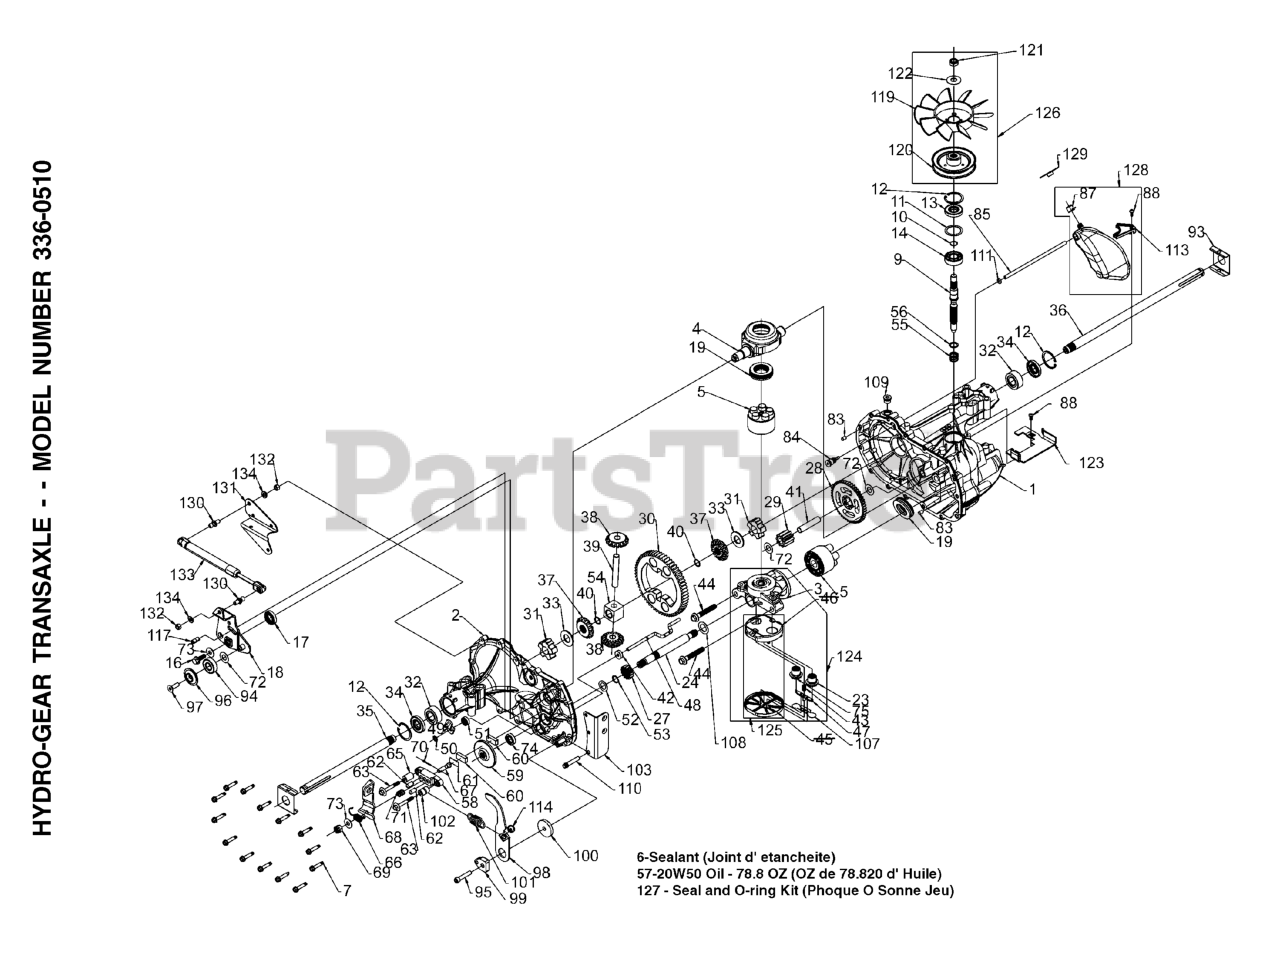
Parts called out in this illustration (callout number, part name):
5	KIT CYLINDER #70331
14	BEARING.BALL(50315)
19	BEARING, THRUST 50551
33	WASHER.HYDRO-GEAR 44875
39	SHAFT.50146
55	SPRING 2003014
60	BRAKE PUCK (44132)
61	PUCK PLATE 44134
62	BRAKE PIN 44127
64	BOLT W/NYLOCK 44433
73	WASHER .34X.88X.06.44130
78	SPRING HELICAL COMP 50277
79	SPACER.HYDRO GEAR 50278
80	LOCKNUT, HEX 5/16-24
87	CAP, VENT ASSY
